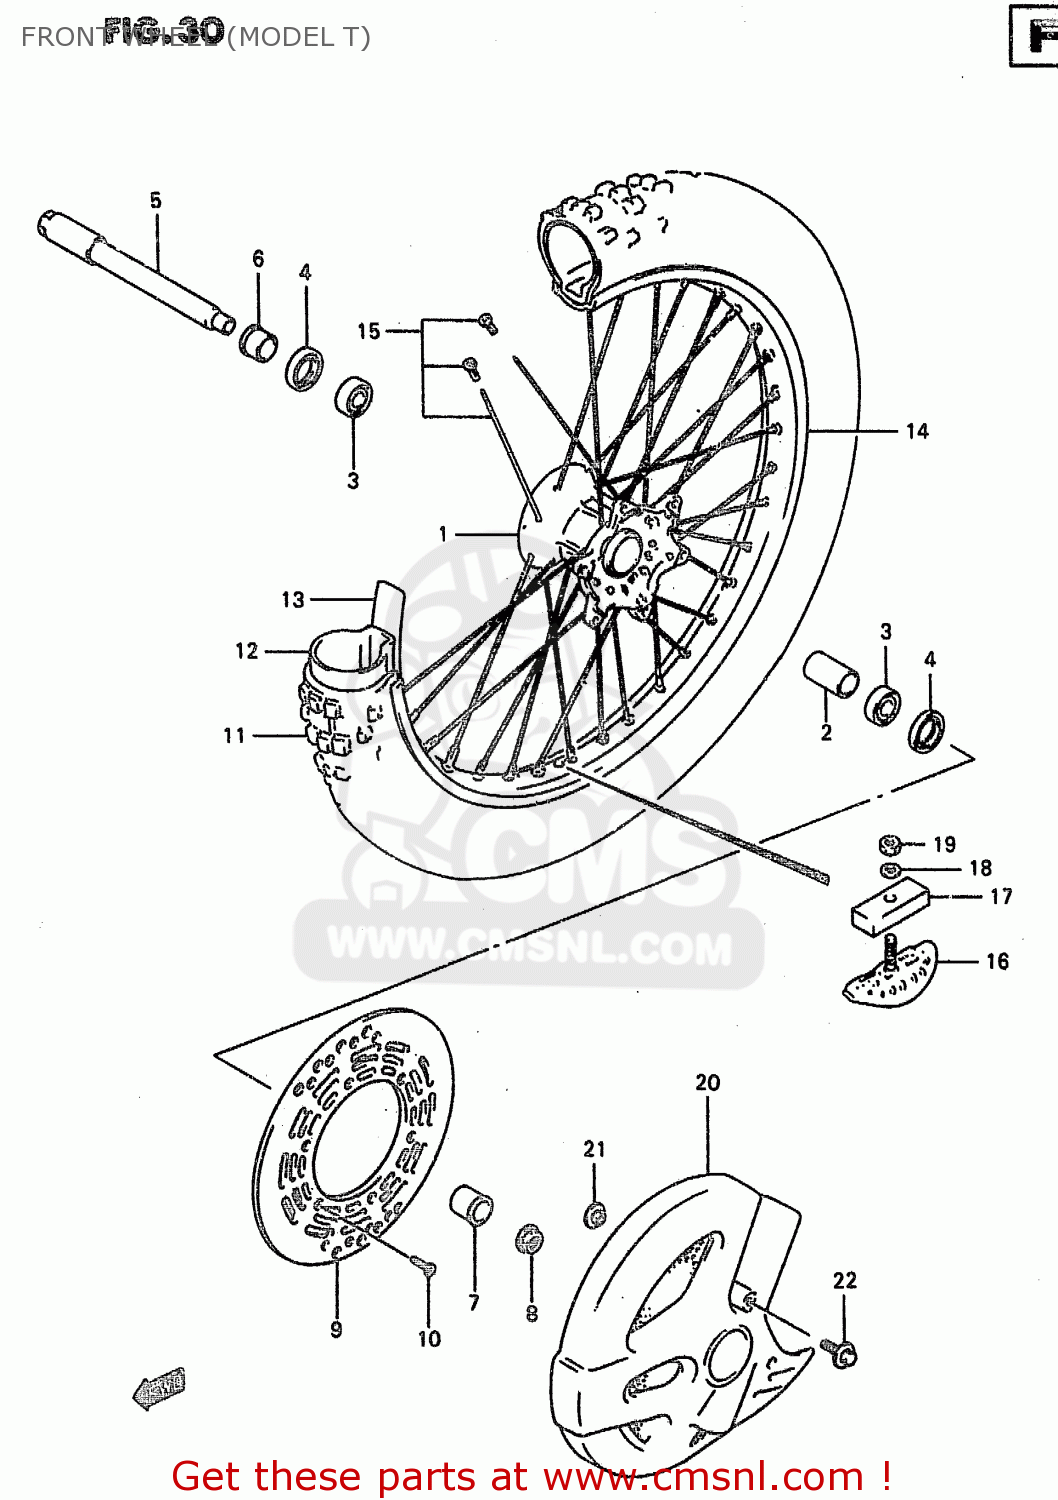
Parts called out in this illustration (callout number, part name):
1	HUB,FR WHEEL
2	SPACER,FR HUB BEARING
3	BEARING
4	SEAL,OIL(25X37X6)
5	AXLE,FRONT
6	SPACER,FRONT AXLE,RIGHT
7	SPACER,FR AXLE,L
8	NUT
9	DISC,FR BRAKE
10	SCREW
11	TIRE,FRONT 80/100-21
12	TUBE
13	PROTECTOR,WHEEL INNER
14	RIM,FRONT WHEEL (1.60X2
15	SPOKE SET,FR WHEEL
16	STOPPER,BEAD
17	CUSHION,BEAD STOPPER
18	WASHER
19	NUT
20	COVER,FRONT BRAKE DISC
21	WASHER
22	BOLT(6X16)
